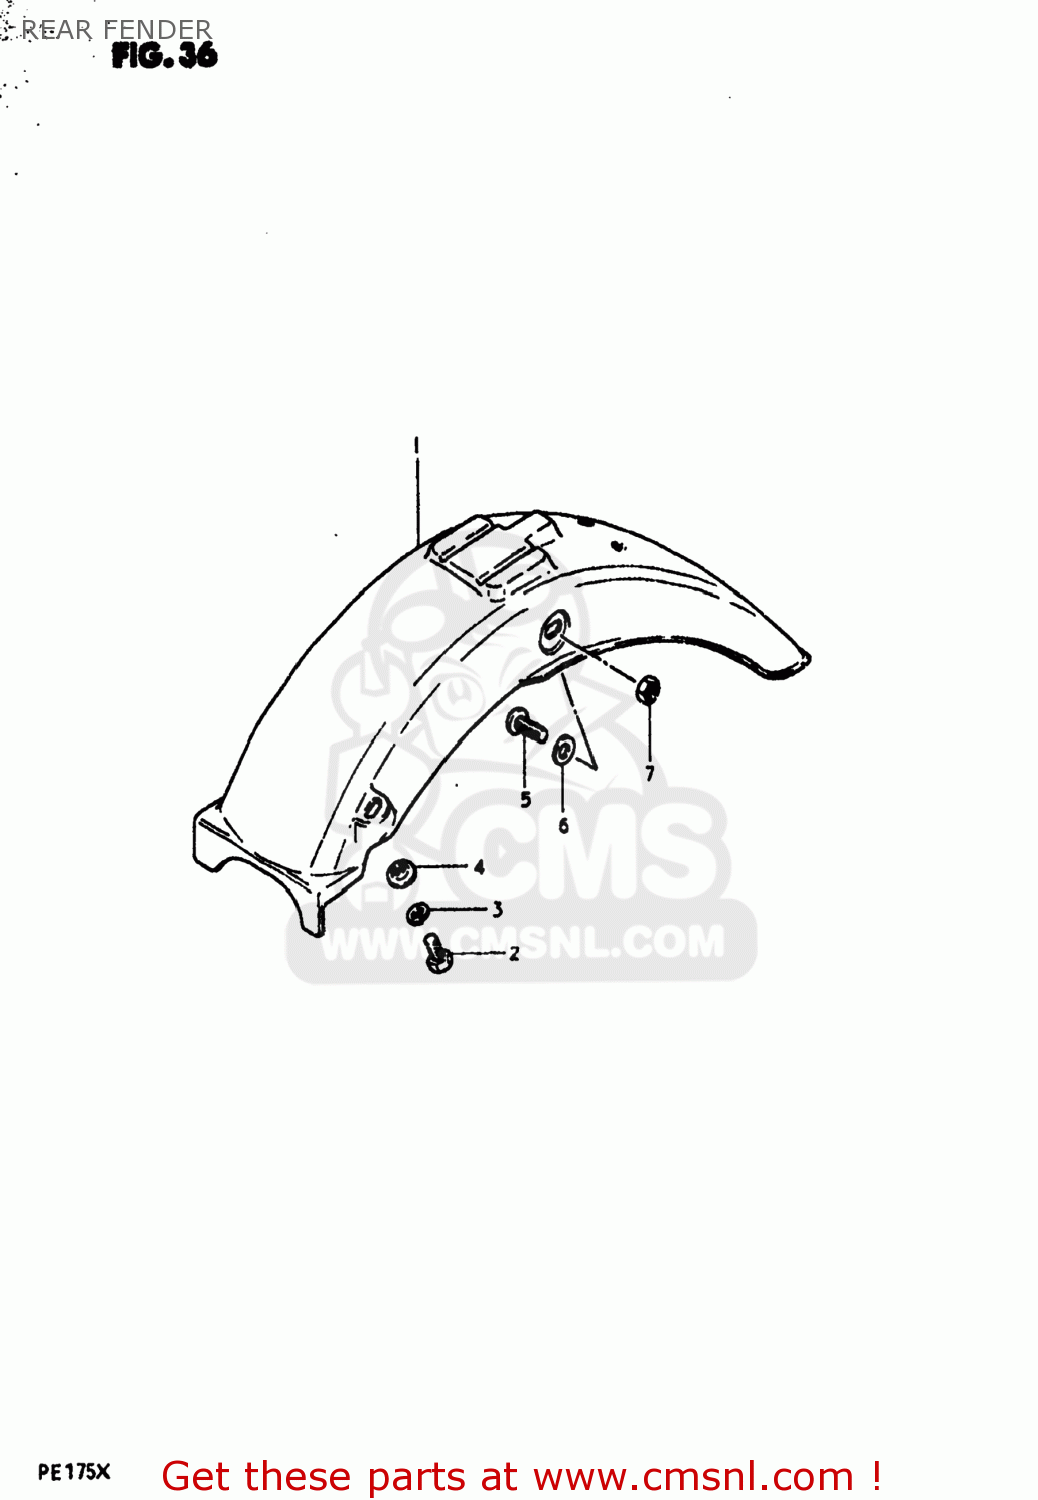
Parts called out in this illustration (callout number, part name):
1	FENDER,REAR
2	BOLT
3	LOCK WASHER
4	WASHER
5	SCREW
6	WASHER (6.5X20X1.2)
7	NUT
